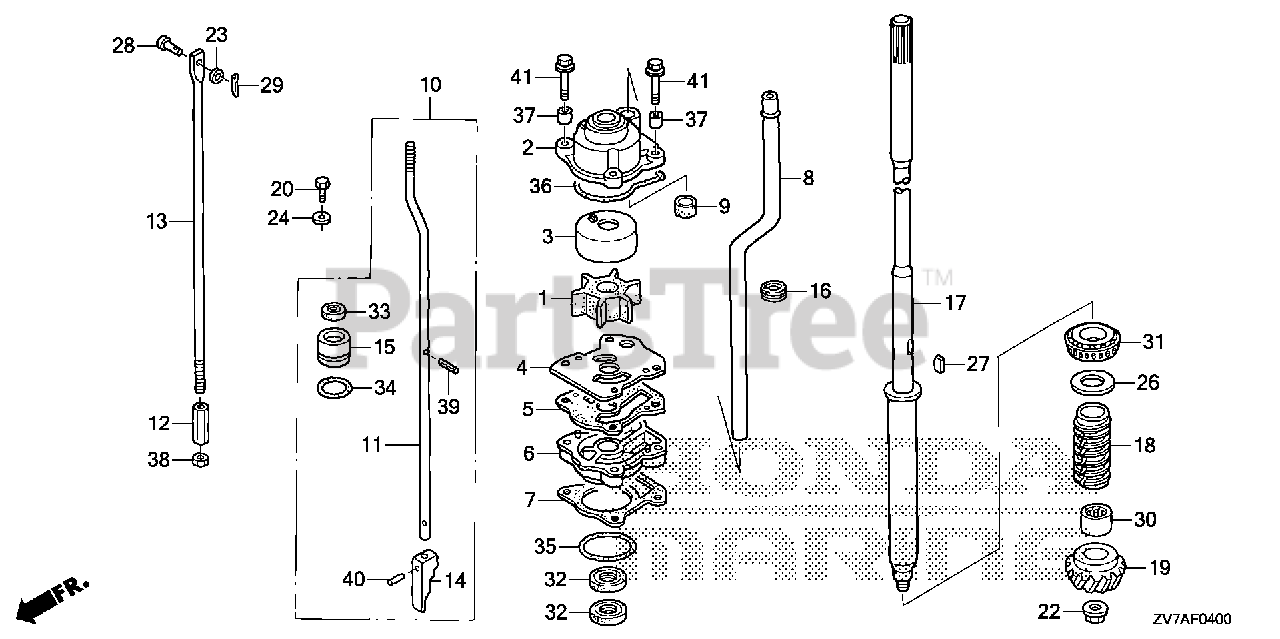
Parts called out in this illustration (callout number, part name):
1	IMPELLER, PUMP
2	HOUSING, IMPELLER
3	LINER, PUMP
4	COVER, IMPELLER
5	GASKET B, IMPELLER
6	HOUSING, WATER PUMP
7	GASKET, WATER PUMP
8	TUBE, WATER (S)
9	RING, WATER TUBE SEAL
10	ROD, SHIFT (S)
11	ROD B, SHIFT (S)
12	JOINT, SHIFT ROD
13	ROD A, SHIFT
15	HOLDER, SEAL
16	GROMMET, EXTENSION CASE
17	SHAFT, VERTICAL (S)
18	SLINGER, OIL
20	BOLT, HEX. (6X12)
22	NUT, SPECIAL (10MM)
23	WASHER, PLAIN (5MM)
24	WASHER, SPECIAL
26	SHIM, GEAR (40X46X0.10) (A)
26	SHIM, GEAR (40X46X0.15) (B)
26	SHIM, GEAR (40X46X0.30) (C)
26	SHIM, GEAR (40X46X0.50) (D)
27	KEY, WOODRUFF (5MM)
28	PIN (5X17)
29	PIN, SPLIT (1.6MM)
30	BEARING, NEEDLE (7/8X11/8X1)
31	BEARING (25X47X15)
32	SEAL, WATER (17X30X7)
33	SEAL, WATER (6MM)
34	O-RING (20.8X2.4)
35	O-RING (41.7X3.5)
36	O-RING, WATER PUMP
37	COLLAR, IMPELLER HOUSING
38	NUT, HEX. (6MM)
39	PIN, SPRING (2X12)
40	ROLLER (2.5X11.8)
41	BOLT-WASHER (6X40)
